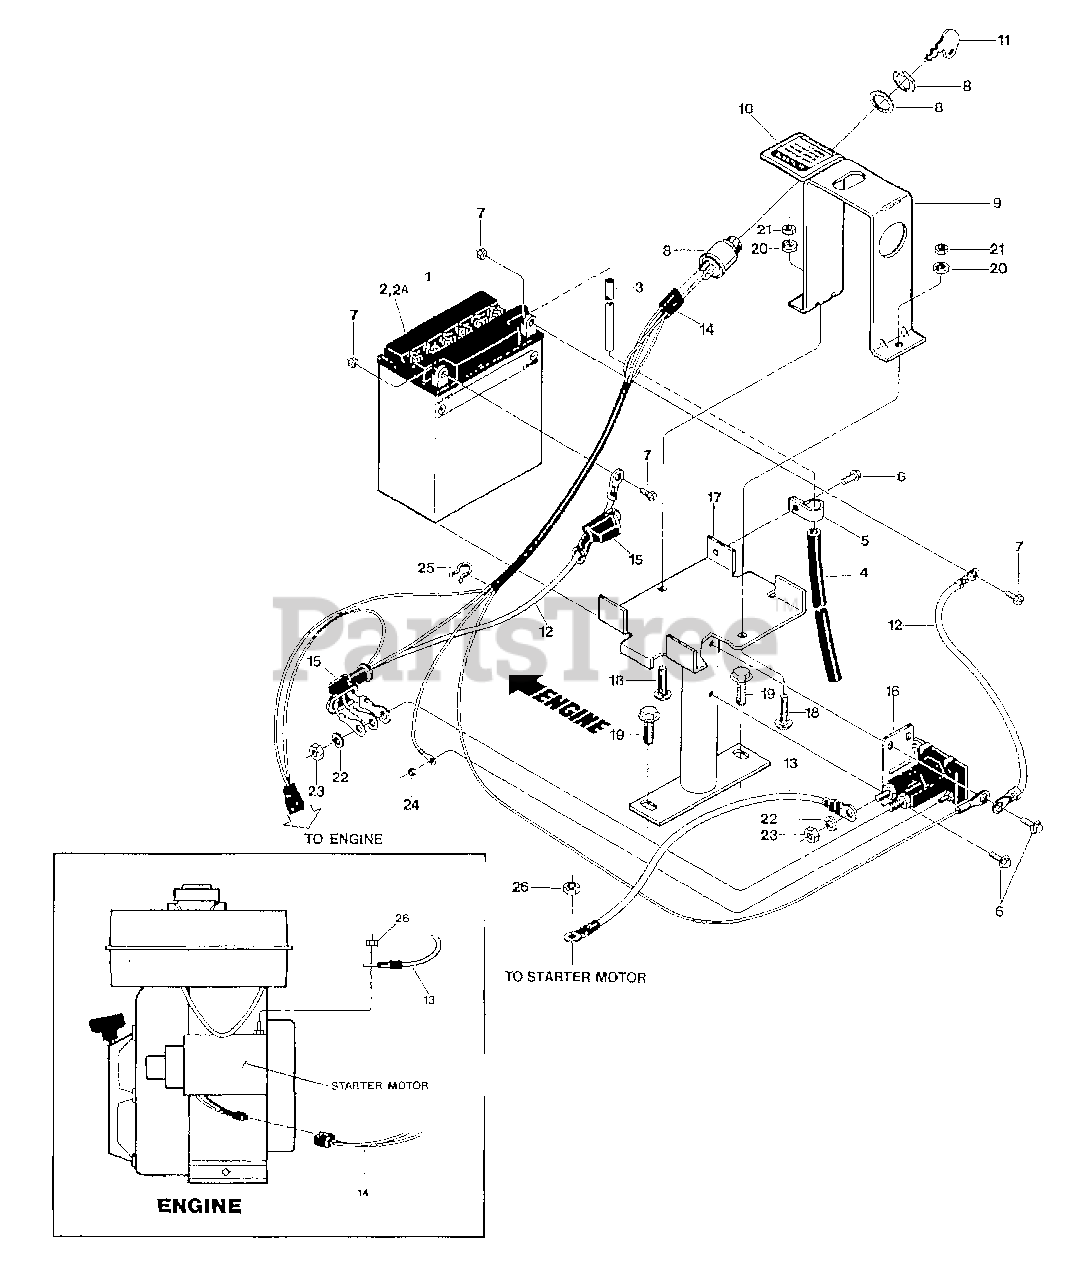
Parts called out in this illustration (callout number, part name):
1	BATTERY
2	CAP-YELLOW
2A	CAP-BATTERY WHITE (PONY)
3	TUBE-VENT BATTERY/HSE
4	TUBING-RUBBER (HARD PLASTIC)
5	CLAMP
6	SCR-HWH 1/4-20 X .5 STH
7	HDW PKG-BATTERY TERMINAL
8	ASSM-KEYSWITCH ELEC TLR
9	KEY PLATE/CLAMP PNT (INCL. DECAL, #10)
10	DECAL-KEYSWITCH TILLER
11	KEY-IGNITION
12	CABLE-BATTERY-12"
13	CABLE-BATTERY 15"
14	ASSM-WIRE HARNESS - AVAIL. AS COMPLETE ASSY. ONLY
15	BOOT-BATTERY CABLE
16	SOLENOID - INCL. NUTS & WASHERS FOR CABLES & WIRES
17	BRKT-BATTERY OPC PNT
18	SCR-CARR 1/4-20X1.25
19	SCR-HFLK 5/16-18X1.00 ZP
20	WASHER-LK .25 ZP
21	NUT-HEX 1/4-20 ZP
22	WASHER-LK .312 ZP
23	NUT-HEX 5/16-24
24	NUT W/LKWASHER #10-32 ZP
25	TIE-TWIST LOCK
26	NUT-HF/LK 1/4-20 ZP
